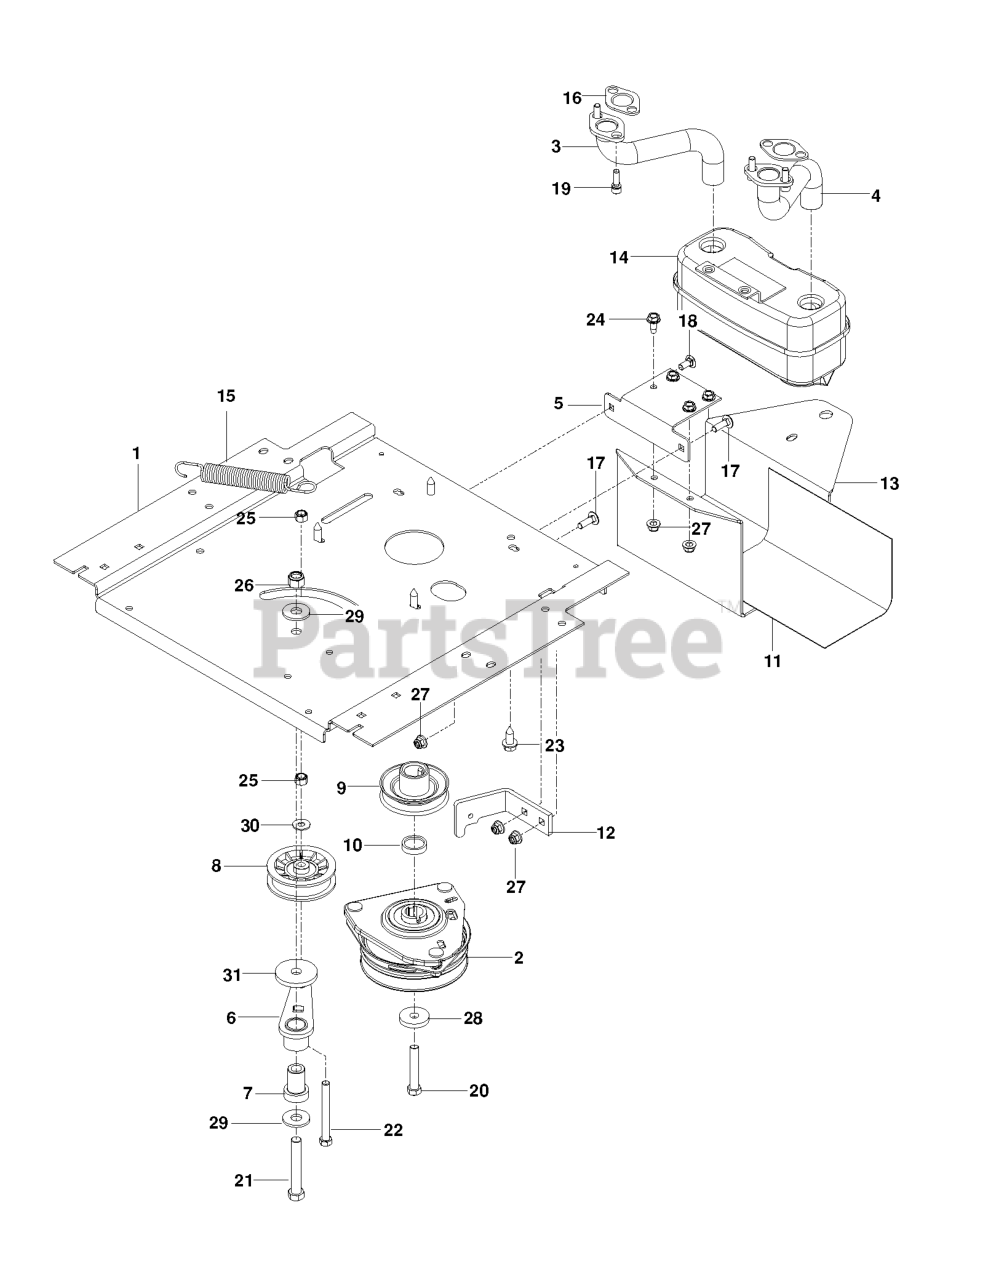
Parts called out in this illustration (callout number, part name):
1	PLATE, ENGINE BLK
2	CLUTCH.ELECTRIC.LT.48"*
3	EXHAUST.TUBE.RH.B&S.TWIN.INTEK
4	EXHAUST.TUBE.LH.BS/TWIN
5	BRACKET, MUFFLER, BLACK
6	IDLER ARM WELDMENT
7	IDLER SPINDLE
8	PULLEY, IDLER RAKE & ZTR
9	RP PULLEY, ENGINE
10	SPACER, HUB PULLEY
11	HEAT SHIELD
12	CLUTCH STOP OGR BLK
13	GUARD.MUFFLER.BLACK
14	MUFFLER ASM TWIN
15	SPRING, DECK DRIVE
16	GASKET.MUFFLER
17	BOLT
18	BOLT 5/16-18 X3/4 ZN/YEL GR 5
19	SCREW.SOCKET.HEAD.5/16-18
20	HCS 7/16-20 X 2.5 GR8
21	HCS 1/2-13 X 3-1/4 GD 5 ZD
22	HCS 3/8-16X3-1/2 TAPBLT GR5 ZD
23	SCREW 3/8-16X1
24	SCREW
25	NUT 3/8-16 NYLOC
26	NUT.LK.W/WSH.1/2.
27	5/16-18 NYLOC FLANGE NUT
29	WASHER.9/16 X 1 3/8 X 12 GA.
30	WASHER
31	HEAVY WASHER
